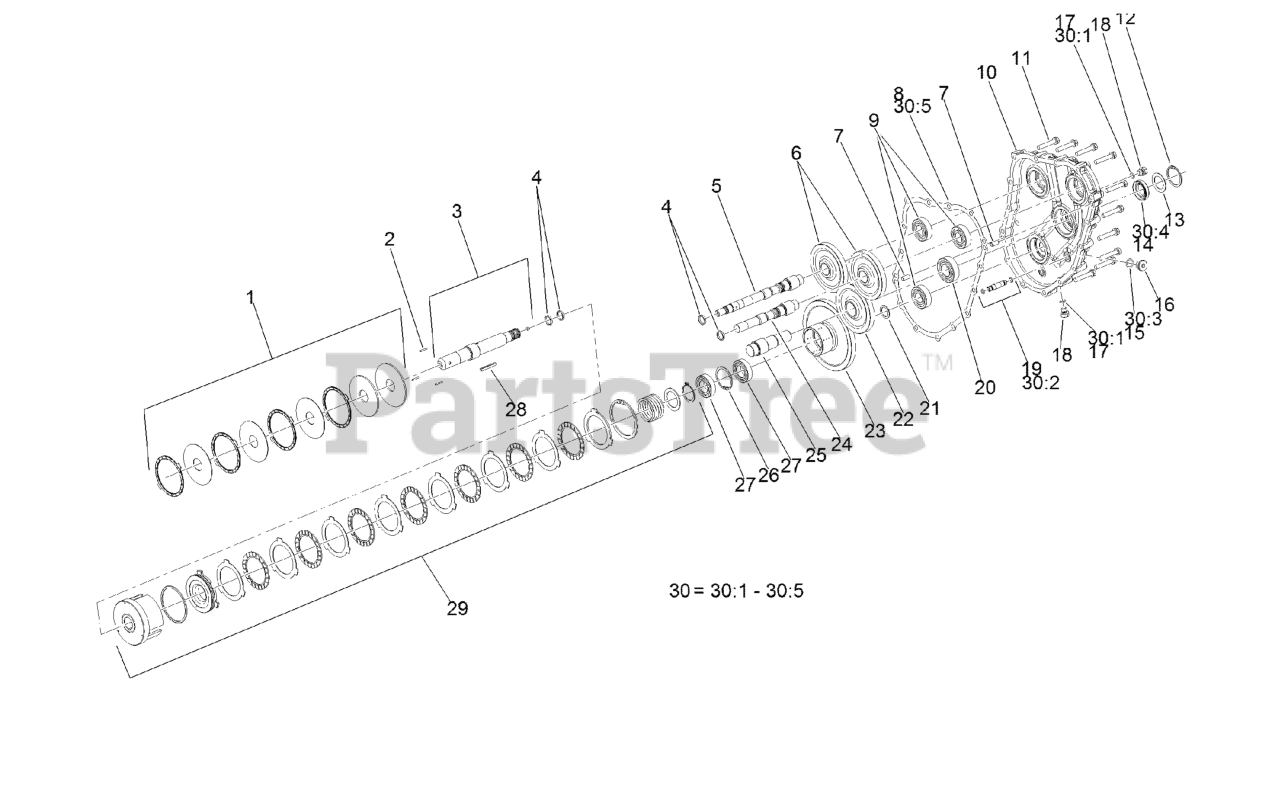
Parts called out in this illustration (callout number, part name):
1	PTO BRAKE ASM
2	ROD-PUSH
3	PTO SHAFT ASM
4	RING-SEAL
5	SHAFT-PUMP
6	GEAR-PUMP
7	PIN-PARALLEL
8	GASKET-HOUSING, GEAR
9	BEARING
10	HOUSING-CASE, GEAR
12	RING-SNAP
15	Packing
16	PLUG-NPTF
17	O RING-PLUG
20	BEARING
22	GEAR-INPUT
23	GEAR-PTO
24	SHAFT-PUMP
25	SHAFT-INPUT
26	RING-SNAP
27	BEARING
29	CLUTCH CYLINDER ASM
30	GEAR HOUSING SEAL KIT
30:1	O RING-PLUG
30:2	O-Ring
30:3	Packing
30:5	GASKET-HOUSING, GEAR
